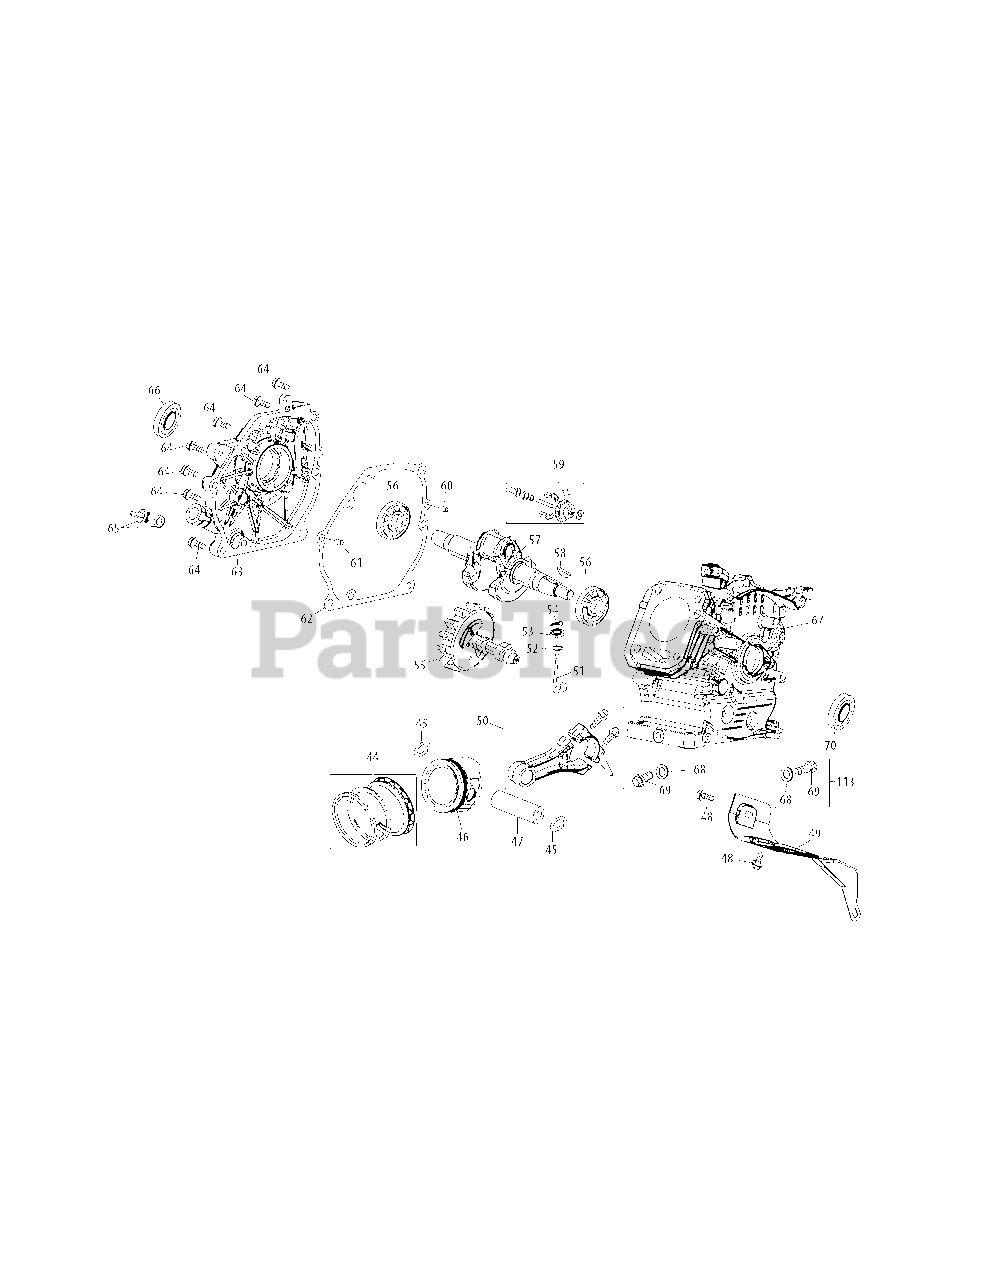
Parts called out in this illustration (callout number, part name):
44	Piston Ring Set
45	Piston Pin Snap Ring
46	Piston
47	Piston Pin
48	Bolt M6×12
49	Air Shield
50	Connecting Rod Assembly
51	Governor Arm Shaft
52	Washer 5.2×1.9
53	Governor Seal
54	Cotter Pin
55	Camshaft Assy.
56	Radial Ball Bearing, 6205
57	Crankshaft Assembly
58	Woodruff Key
59	Governor Gear/Shaft Assembly
60	Dowel Pin 7×14
61	Dowel Pin 9×14
62	Crankcase Cover Gasket
63	Cover Comp, Left Crankcase
64	Bolt M8×32
65	Oil Fill Plug Assembly
66	Oil Seal, 25×41.25×6
67	Short Block
68	Washer 10×16×1.5
69	Oil Drain Plug
70	Oil Seal 25×41.25×6
113	Oil Drain Plug & Washer Assembly
